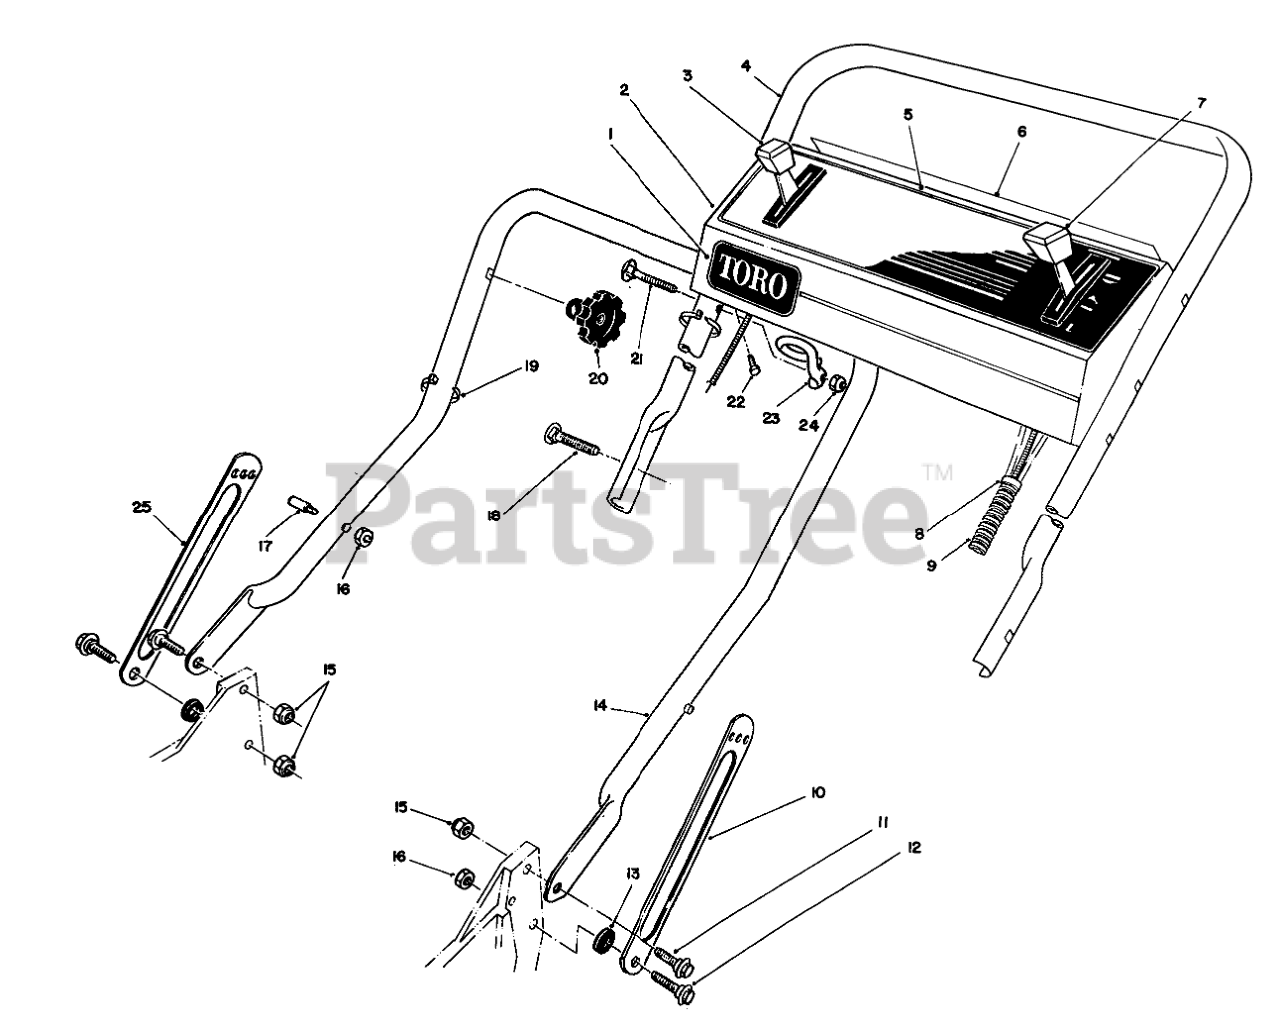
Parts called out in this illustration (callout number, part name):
1	DECAL - TORO
2	Panel-Control(Incl. Ref. #5)
3	Control-Ground Speed
4	UPPER HANDLE
5	DECAL - INSTRUCTIONS
6	DECAL - PANEL, REAR
7	THROTTLE CONTROL
8	FITTING-RING
9	CONTROL CABLE COVER
10	LH HANDLE LATCH
11	SCREW-SHOULDER
12	SCREW-SHOULDER
13	SPACER
14	LOWER HANDLE ASM
15	NUT-LOCK, NI
16	NUT-LOCK, NI
17	HANDLE PIN
18	5/16-18 X 2 HNDLE SCREW
19	TIE-CABLE
21	HANDLE SCREW
22	SCREW-HWHTF
23	Guide
24	NUT-LOCK, NI
25	RH HANDLE LATCH
